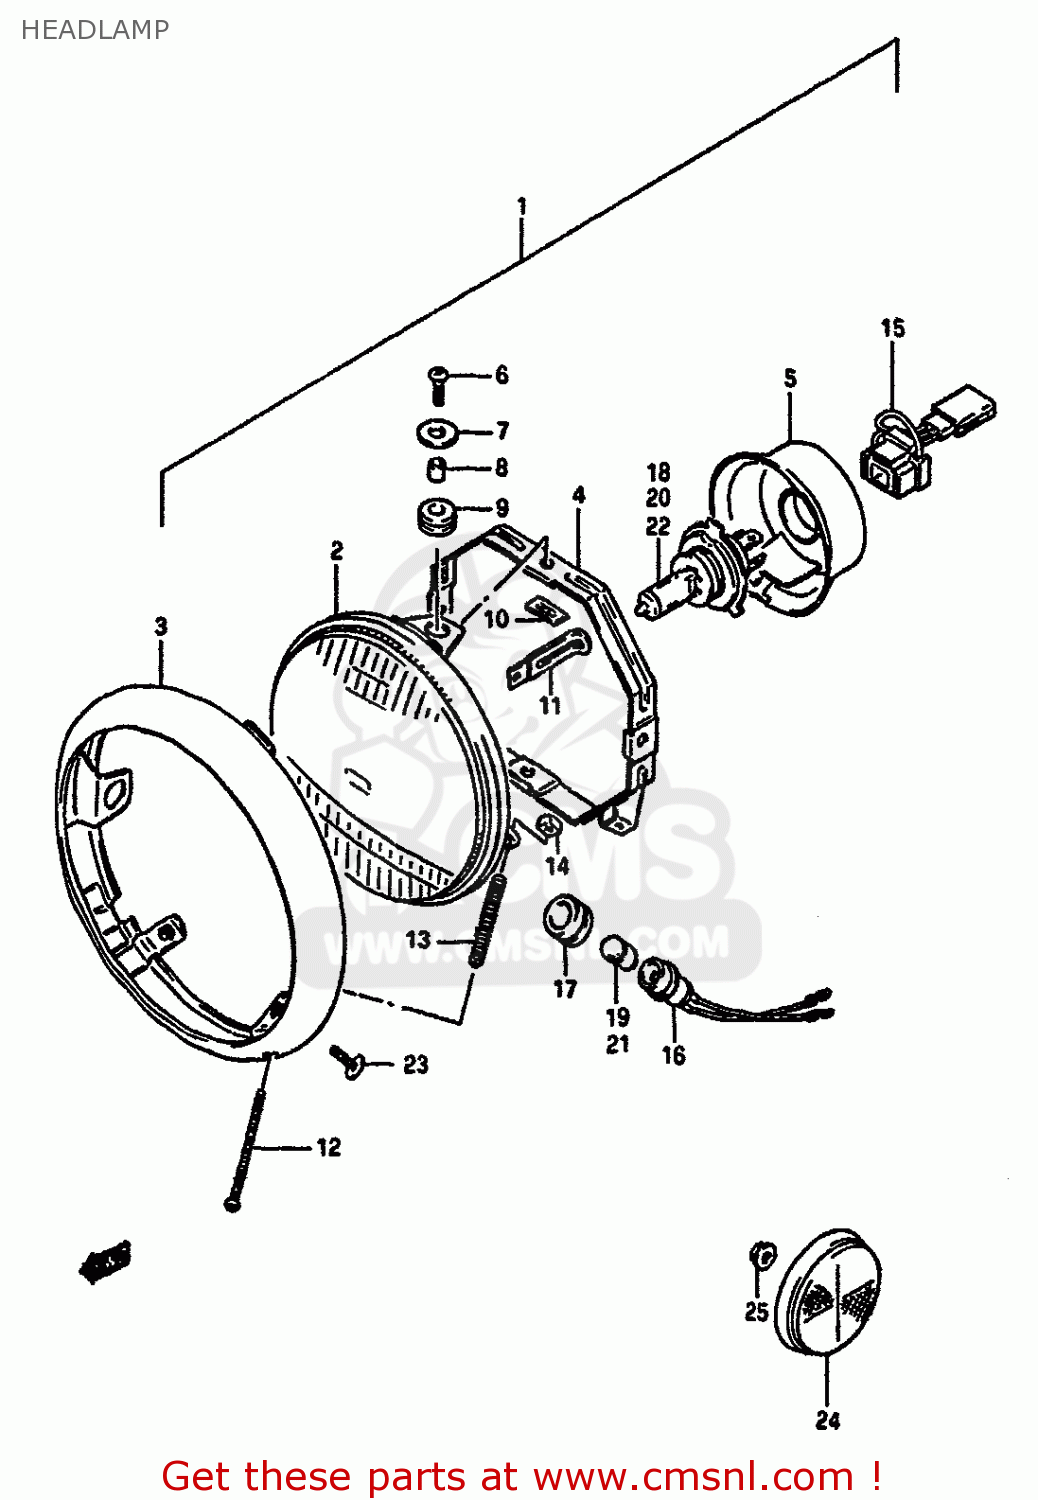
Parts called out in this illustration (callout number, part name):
1	HEADLAMP ASSY
2	LAMP UNIT
3	RIM
4	RING,MOUNTING
5	COVER,SOCKET
6	SCREW
7	WASHER
8	SPACER
9	CUSHION
10	NUT
11	CLAMP
12	SCREW,HEADLAMP ADJUST
13	SPRING,HEADLAMP ADJUST
14	NUT
15	SOCKET
16	SOCKET
17	JOINT,RUBBER
18	BULB(12V60/55W,H4)
19	BULB(12V3.4W,STANLEY,A72A)
20	BULB (12V, 60/55W, H4)
21	BULB(12V4W)
22	BULB(12V60/55W,H4)
23	SCREW(5X12)
24	REFLECTOR,REFLEX FR
25	NUT
